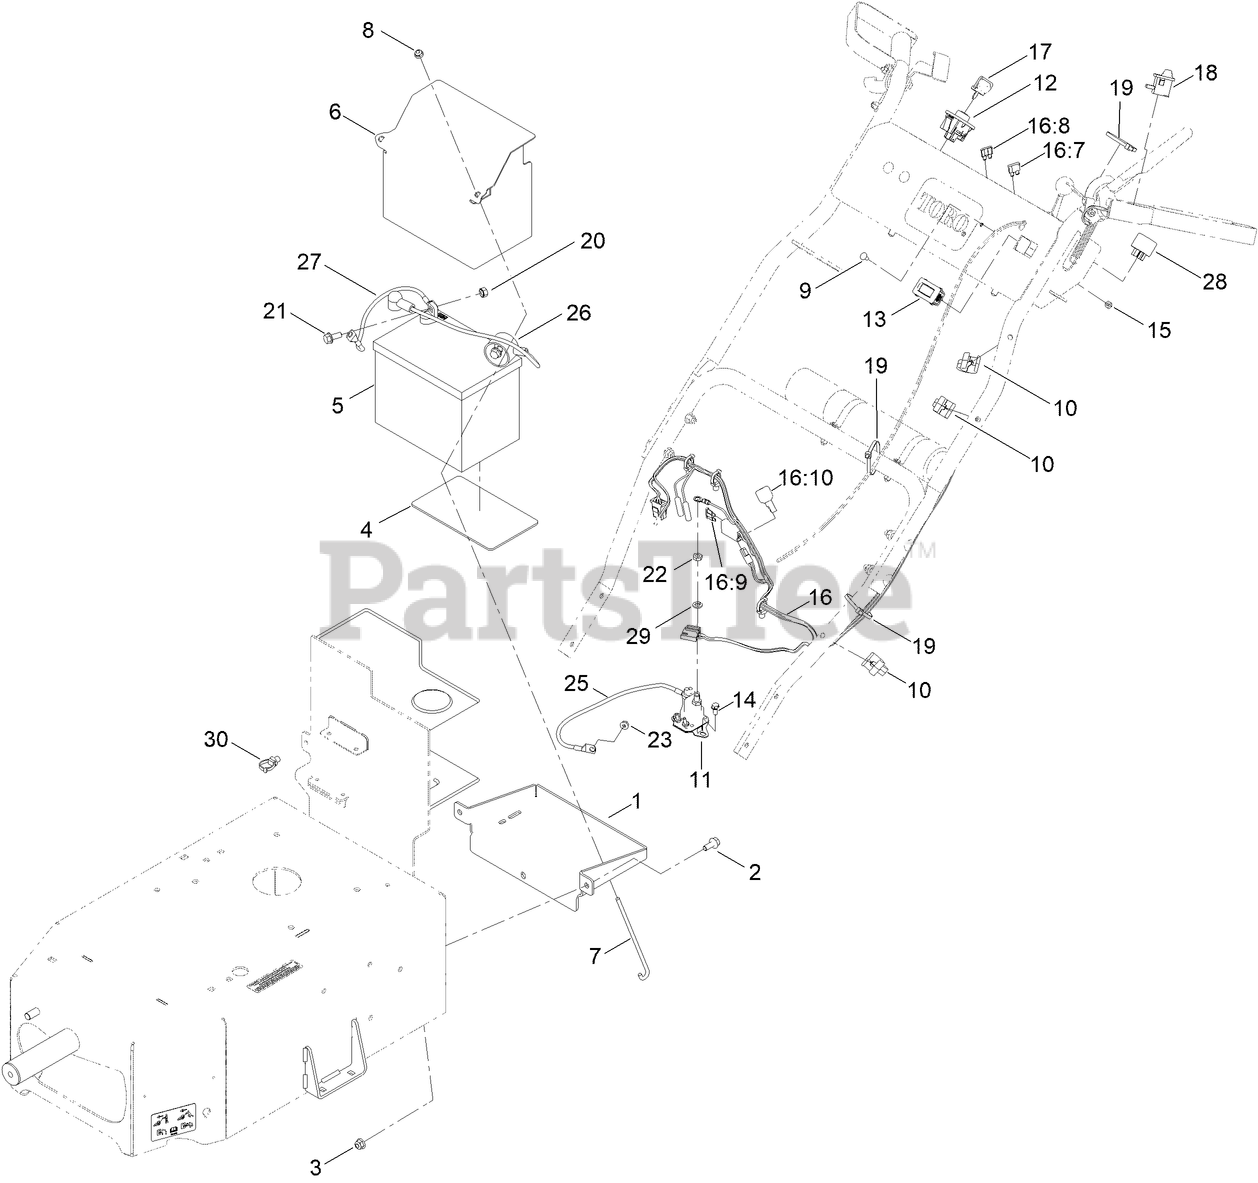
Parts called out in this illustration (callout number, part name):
1	TRAY-BATTERY
2	SCREW-HHF
3	NUT-HF, NI
4	PAD-SKID, ANTI
5	BATTERY
6	TRAY-BATTERY
7	BOLT-HOLDDOWN
8	NUT-HF
9	BOLT-CARR
10	GUIDE-CABLE
11	SOLENOID
12	SWITCH-IGNITION
13	HOURMETER
14	SCREW-HWH
15	NUT-LOCK, NI
16	HARNESS-WIRE
16:7	FUSE-BLADE, 10 AMP
16:8	FUSE-BLADE, 25 AMP
16:9	FUSE-BLADE, 30 AMP
17	KEY-IGNITION
18	SWITCH-PLUNGER
19	TIE-CABLE
20	NUT-KEPS
21	SCREW-HHF
22	NUT-JAM
23	NUT-HF
25	CABLE-BATTERY, POSITIVE
26	CABLE-BATTERY, POSITIVE
27	CABLE-BATTERY, NEGATIVE
28	RELAY
29	WASHER-LOCK
30	CLIP-TIE
